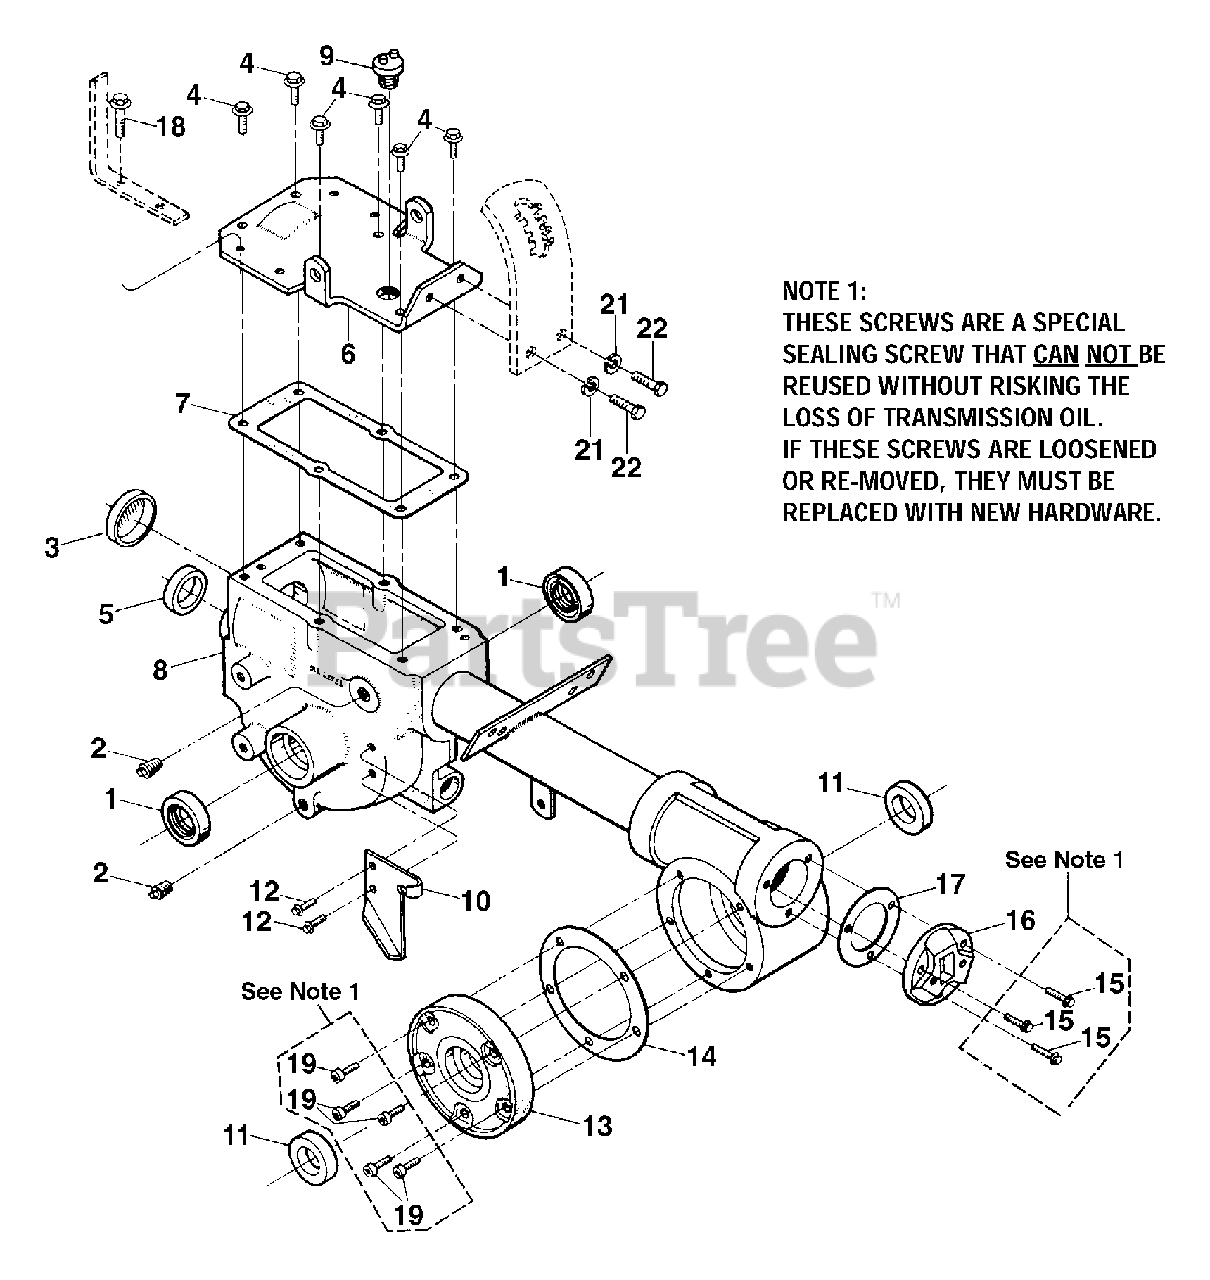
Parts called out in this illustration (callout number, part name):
1	Oil Seal-double lip, wheel shaft
2	Plug-pipe, 1/4
3	Seal-transmission bore
4	Screw- flanged hex hd., 5/16-18 x 3/4
5	Oil Seal-input pinion shaft
6	Cover-top of transmission
7	Gasket-transmission top cover
8	Transmission case, tube and rear housing assembly
9	Plug-gear oil fill hole
10	Plate-wheel drive cable mounting
11	Oil Seal-tiller shaft
12	Screw- flanged hex hd., 5/16-18 x 5/8
13	Cover-tiller housing, left side
14	Gasket-tiller housing cover, .010
15	Screw Kit:
16	Cap-rear bearing
17	Gasket-rear bearing cap, .010 thick
18	Screw-flanged hex hd., 5/16-18 x 1
19	Screw Kit:
21	Lockwasher-3/8
22	Screw-hex hd., 3/8-16 x 3/4
